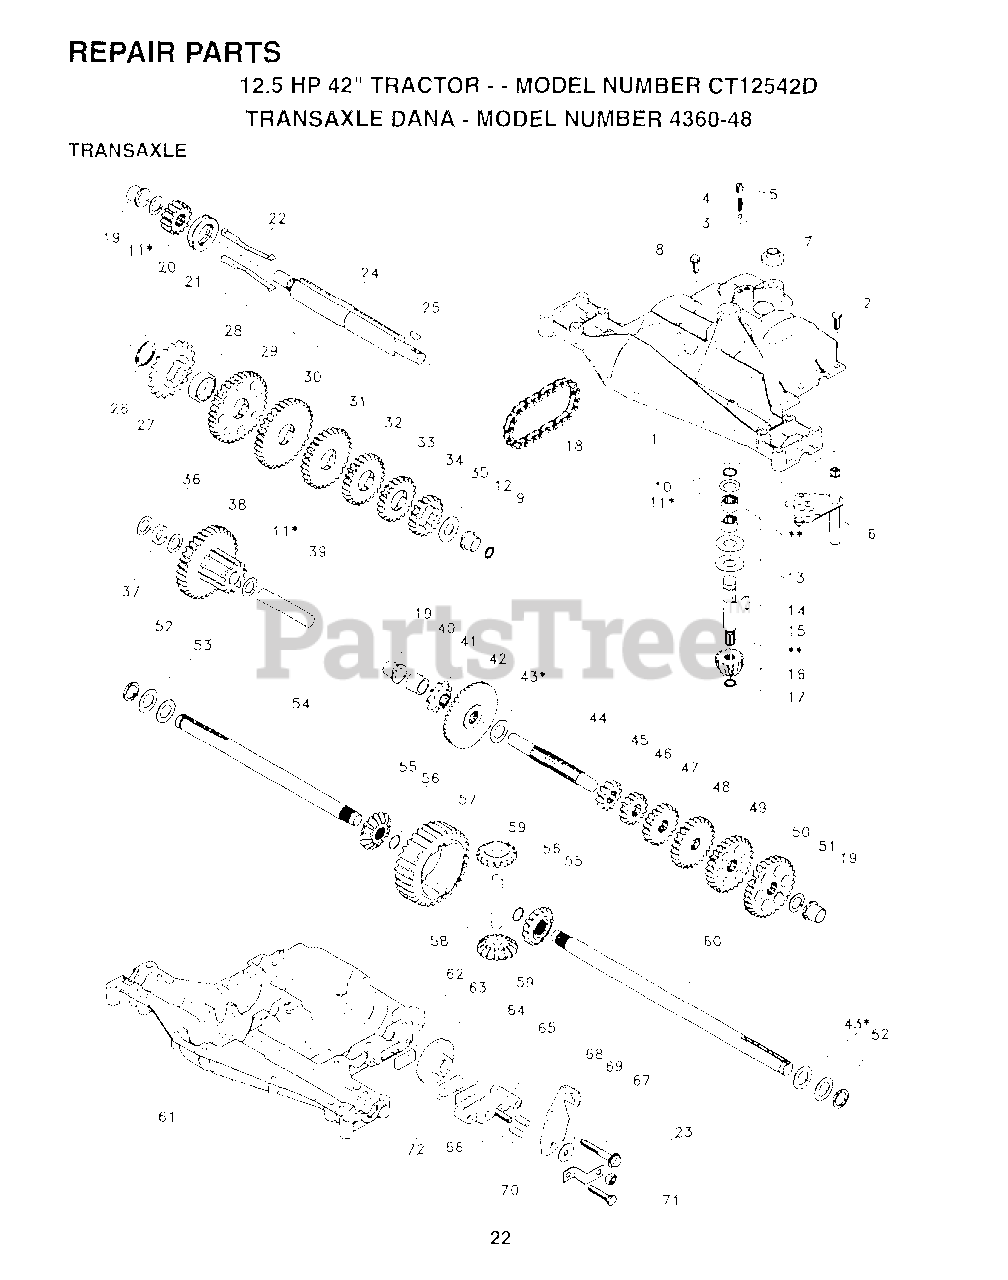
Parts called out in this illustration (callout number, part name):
4	"SPRING, DETENT LT"
5	"SCREW, SET LT"
6	KIT SHIFTER ASM
7	SHIFTER BOOT
8	SCREW TAP W/SEAL
9	SQUARE RING
10	RETAINING RING LT
11	ASM KIT SHIM 4689
12	"FLANGE, BEARING"
13	WASHER T
14	WOODRUFF KEY
15	AS KIT INPUT SHFT
16	PINION 14T T
17	"RING,RETAINING LT"
18	"CHAIN,24 PTCH LT"
19	BEARING.FLNG.5510
20	GEAR SPUR 14T
21	COLLAR CLUTCH
22	ASM KIT CLTCH KEY
23	NUT.LOCK.5/16-24
24	SHAFT INTERM
25	WOODRUFF KEY
26	"RING,RETAINING LT"
27	SPROCKET 18T T
28	SPACER YT
29	KIT.GEAR.12/37TH
32	GEAR 25T LT
33	GEAR SPUR 22 TT
34	SPUR GEAR 19T
35	"WASHER, PLAIN LT"
36	WASHER 025
37	SPACER
38	ASSM GEAR COMB
39	SHAFT IDLER
40	SPACER T
41	SPROCKET 9T LT
43	ASM KIT SHIM
44	SHAFT T
48	"GEAR, SPUR 25T LT"
49	GEAR 28T T
50	"GEAR, SPUR 31T LT"
51	WASHER 060
52	NEOPRENE WASHER
53	WASHER 031
55	GEAR 15T T
56	"RING,RETAINING LT"
58	SHAFT T
59	GEAR 1ST T
62	PUCK T
63	BRAKE DISC. T
64	SPACER LT
66	PIN T
69	WASHER LT
71	"SCREW, TAPPING LT"
72	PUCK T
